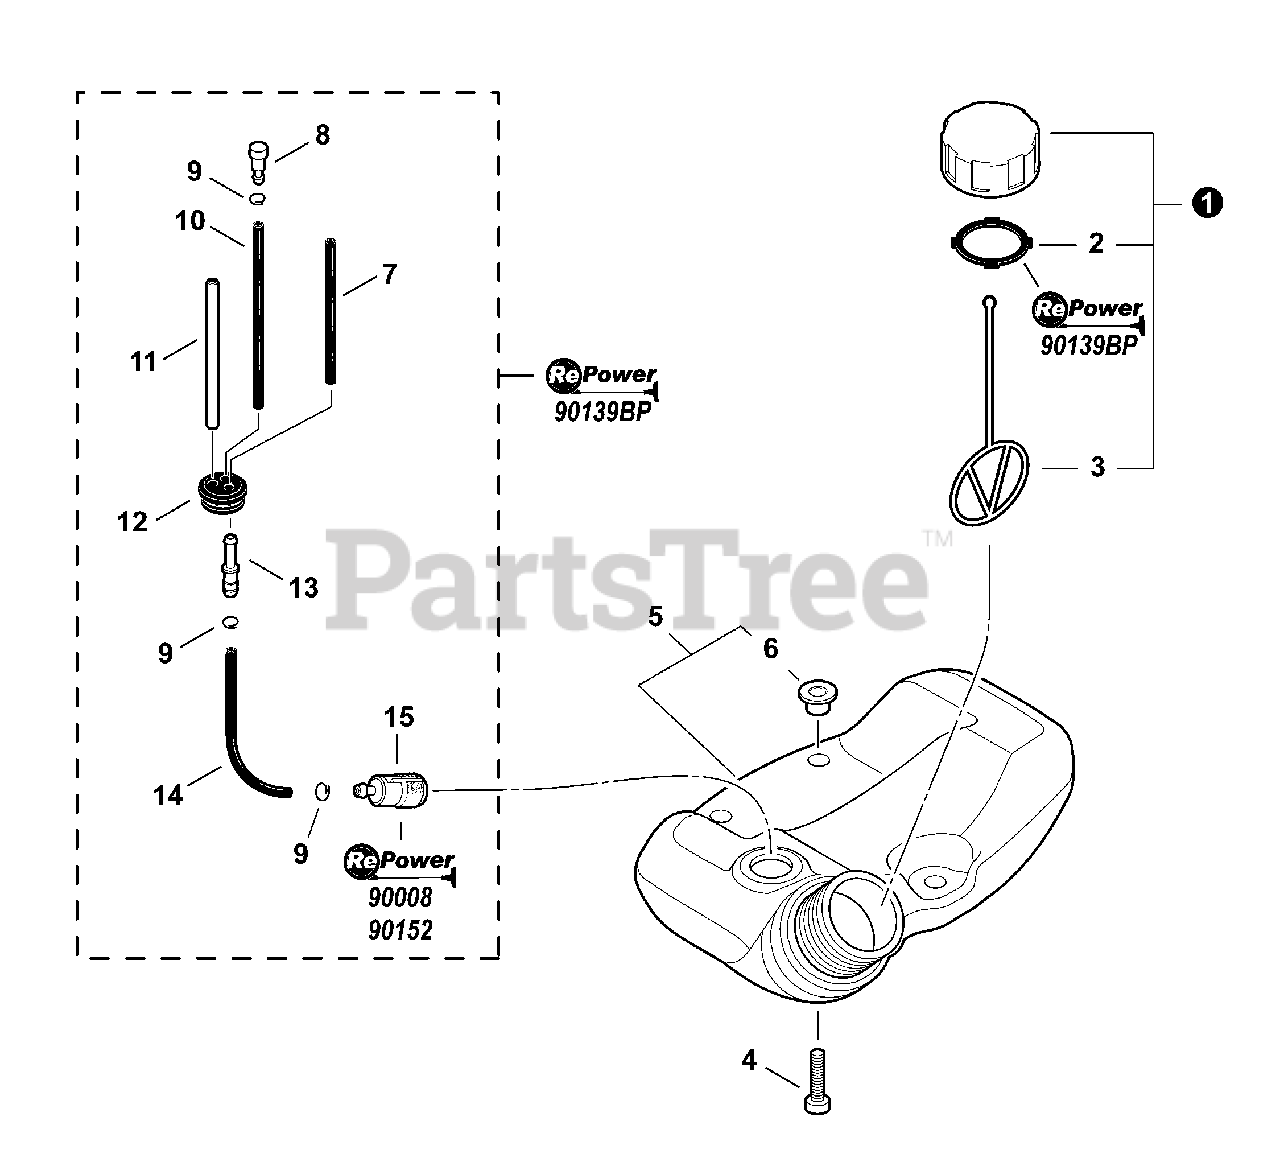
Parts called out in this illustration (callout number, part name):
1	CAP ASSY, FUEL
2	GASKET, FUEL CAP
3	CONNECTOR, CAP L= 123
4	BOLT, TORX 5×20
5	TANK ASSY, FUEL
6	COLLAR 5
7	PIPE, FUEL 3×5×74 BLACK
8	VENT ASSY
9	CLIP Ø6
10	PIPE, FUEL 3×5×90 BLACK
11	PIPE, FUEL 3×6×80 CLEAR
12	GROMMET, FUEL Ø5
13	CONNECTOR, PIPE Ø5ר3.5
14	PIPE, FUEL 3×5×110 BLACK
15	FILTER, FUEL
